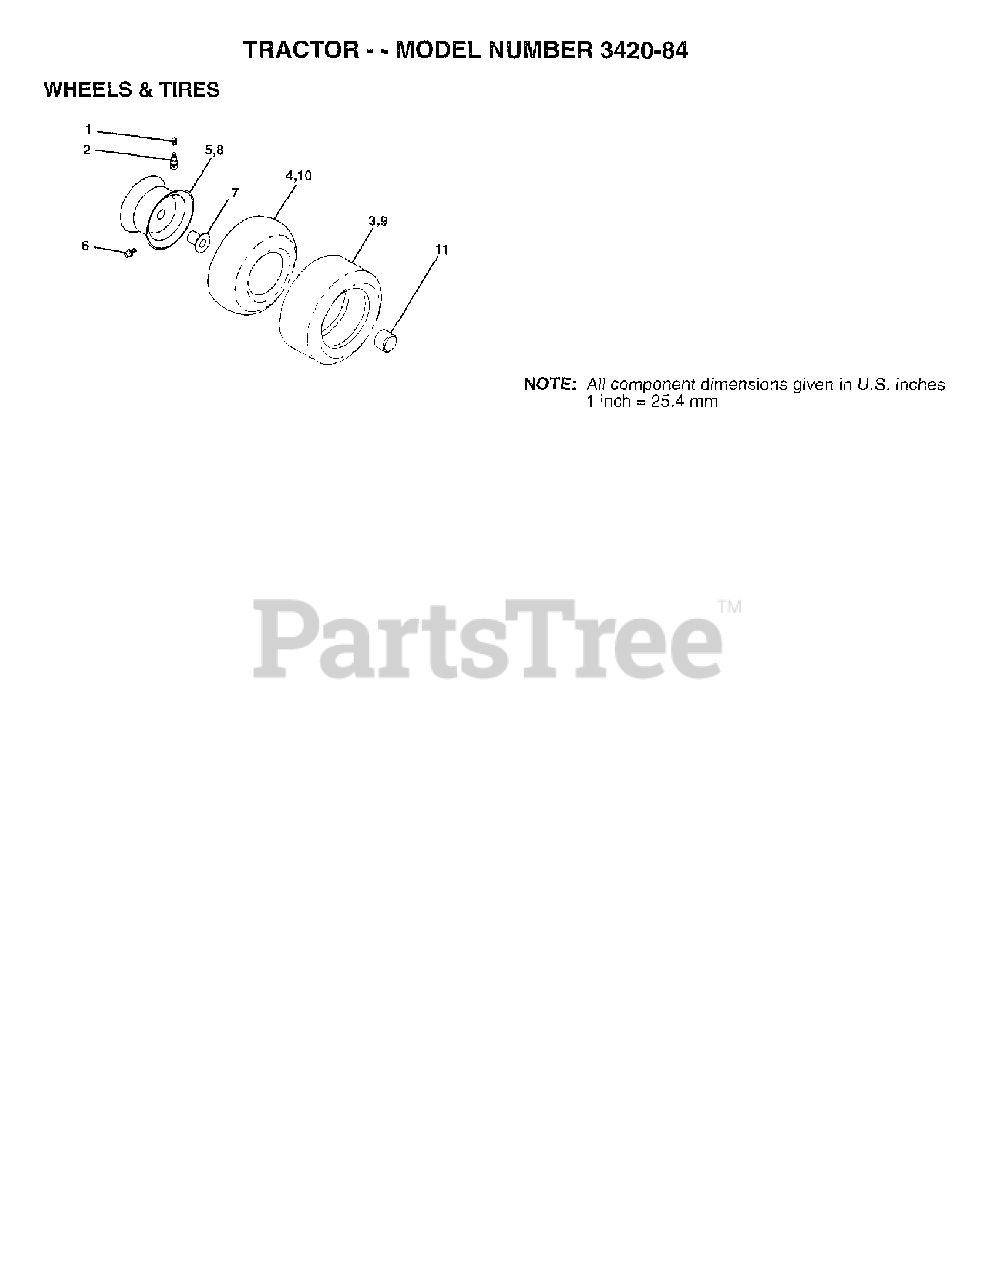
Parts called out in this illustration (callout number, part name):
1	VALVE CAP
2	VALVE STEM LT
3	TIRE HEAVY DUTY
4	TUBE.5.3/4.5/6
5	RIM.ASM.6".FRONT.SILVER
6	FITTING LT
7	BEARING T
8	RIM 8" SILVER
9	TIRE 20X8-8 TURF SAVER
10	TUBE - UNIVERSAL FOR 8" RIM
11	CAP.HUB.FRONT.LT.BLACK
